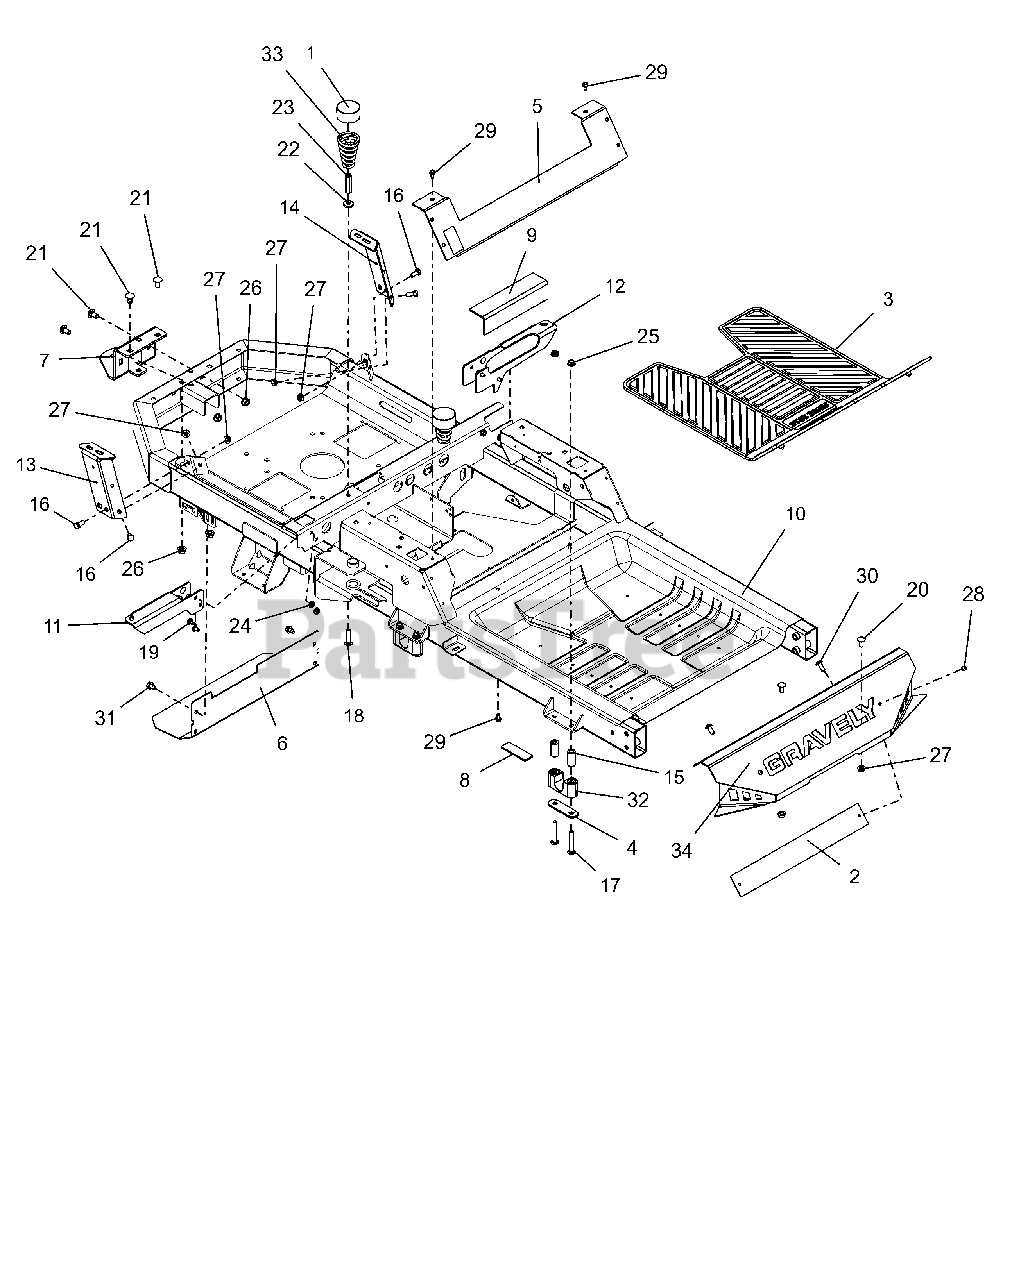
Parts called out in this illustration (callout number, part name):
2	PLATE, BACK FOOT-REST XL
3	FLOOR MAT, RUBBER - GRAVELY
4	PLATE, BEARING SUPPORT
5	PLATE, SEAT KICK
6	HEAT, SHIELD
7	BRKT, HITCH TONGUE
8	PAD,RBR 1.0"X3.0" W/ADHESIVE
9	PAD, RUBBER-TANK
10	KIT, ZT-X/XL FRAME SERVICE
11	BRKT,CROSS EXTENSION - LH
12	BRKT,CROSS EXTENSTION - RH
13	MOUNT,FENDER-RH EXTENSION
14	MOUNT,FENDER-LH EXTENSION
15	SPACER, .323 X .698 X 1.441
16	@BLT-HEX .31-18X.75 GR5 YWZC
17	BLT-RDHDSQSHNK .31-18X2.25 YWZ
18	@BLT-RDHDSQNK .31-18X1.50 G5YZ
19	BLT-RDHDSQSHNK.25-20X.50 YWZC
20	@BLT-RDHDSQNK .31-18X.75 G5YZ
21	@BLT-RDHDSQNK .38-16X.75 G5YZ
22	WSHR-FL-STL .328X.87X.179 YWZC
23	NUT, COUPLING 5/16-18 X 1 3/4
24	NUT-LK-CTR-FLG .25-20 YWZC
25	@NUT-LK-CTR-FLG .31-18 YZ GR F
26	@NUT-LK-TOP-FLG .38-16 YWZC
27	@NUT-LK-TOP-FLG .31-18 YWZC
28	RIVET, .1875 AL/AL .126-.250
29	SCR-TAP .25-20X.50 HWH TR YWZ
30	SCR-RDHDSKTAP .31-18 X .75
31	@SCR-TAP .31-18X.50 HWH TR YWZ
32	BSHG, DECK LIFT PIVOT
33	SPRING, SEAT
34	KIT,FOOTPLATE W/DECAL G- XL
